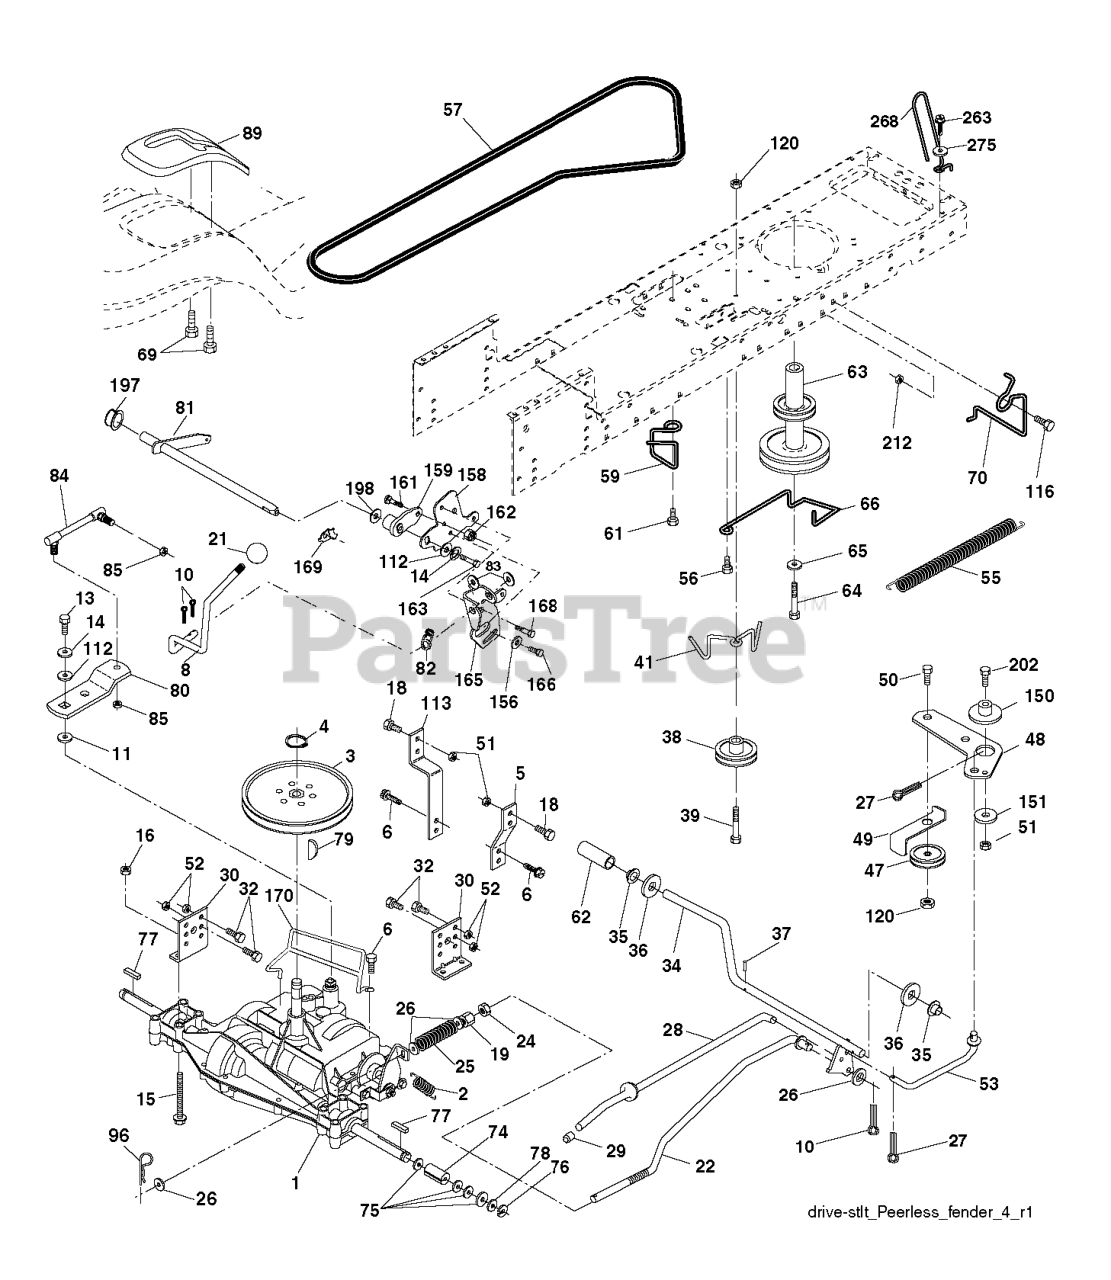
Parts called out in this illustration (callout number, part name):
2	SPRING,BRAKE RETURN
3	PULLEY TRANS
4	RETAINING RING LT
5	STRAP TORQUE
6	SCREW 5/16"
8	ROD SHIFT FENDER ADJUST LT
10	PIN COTTER
11	WASH-SHFT PLT LT
13	BOLT 1/4-28X3/4
14	LOCKWASHER
15	BOLT HEX 5/16-18 GR 5
16	NUT.71038.31-18.HEX.NYLOCK
19	NUT
21	KNOB T (1/2-HOLE)
24	NUT
25	SPRING ROD LT
26	WASHER
27	COTTER PIN
28	ROD, PARKING BRAKE
29	PLUNGER CAP
30	BRKT, MOUNT TRNSAXLE
32	BOLT
34	SHAFT, FOOT PEDAL
35	BEARING.NYLON
37	DRIVE PIN
38	PULLEY IDLER COMPOSITE
41	KEEPER, BELT IDLER
47	IDLER PULLEY
48	BELLCRANK, CLUTCH
49	RETAIN BELT
50	BOLT.3/8-16X1.50
52	LOCKNUT
53	LINK.CLUTCH.7.66.2005
55	SPRING, RETURN LT
56	SCREW.3/8-16
57	BELT, V GROUND DRIVE 95 25
59	KEEPER, BELT CENTER
61	SCREW 3/8-16X.875
62	PEDAL COVER T
63	ENGINE PULLEY
64	BOLT HEX 7/16-20X4-1/4"
65	LOCKWASHER
66	KEEPER BELT ENGINE
69	SCREW.HI-LO.CONSOLE
70	KEEPER BELT ENG
74	SPACER AXLE
77	SQUARE KEY
79	KEY STD (1373) DANA
81	SHAFT ASM CROSS TAPERED
82	SHIFT SPRING
83	WASHER
84	LINK.TRNSAXLE
85	NUT LOCK CENTER 1/4 -28 FNTHD
89	CONSOLE.SVC.SHIFT.LTST.5SP.BLK
96	RETAINER M
113	STRAP TORQUE LH LT
116	BOLT D
120	NUT LOCK FLG 3/8-16 UNC
150	SPACER, RETAINER
151	WASHER 12/32X2X10GA
156	WASHER.SRRTD.5/16
158	BRACKET
159	RB HUB.SHIFT
161	BOLT
162	NUT.CROWNLOCK.1/4
165	RP BRACKET
166	CAPSCREW.HXHD.FLG.5/16-18X.625
168	BOLT.SHOULDER.5/16-18X
169	PLATE.FASTENING.CROSS.SHAFT
170	KEEPER BELT T/A
197	NYLINER SNAP 5/8" ID
198	WASHER.NYL.7/8IDX.105"HYD CR
212	NUT
263	SCREW, 3/8-16X3/4
268	GUARD MUFFLER
275	WASHER
